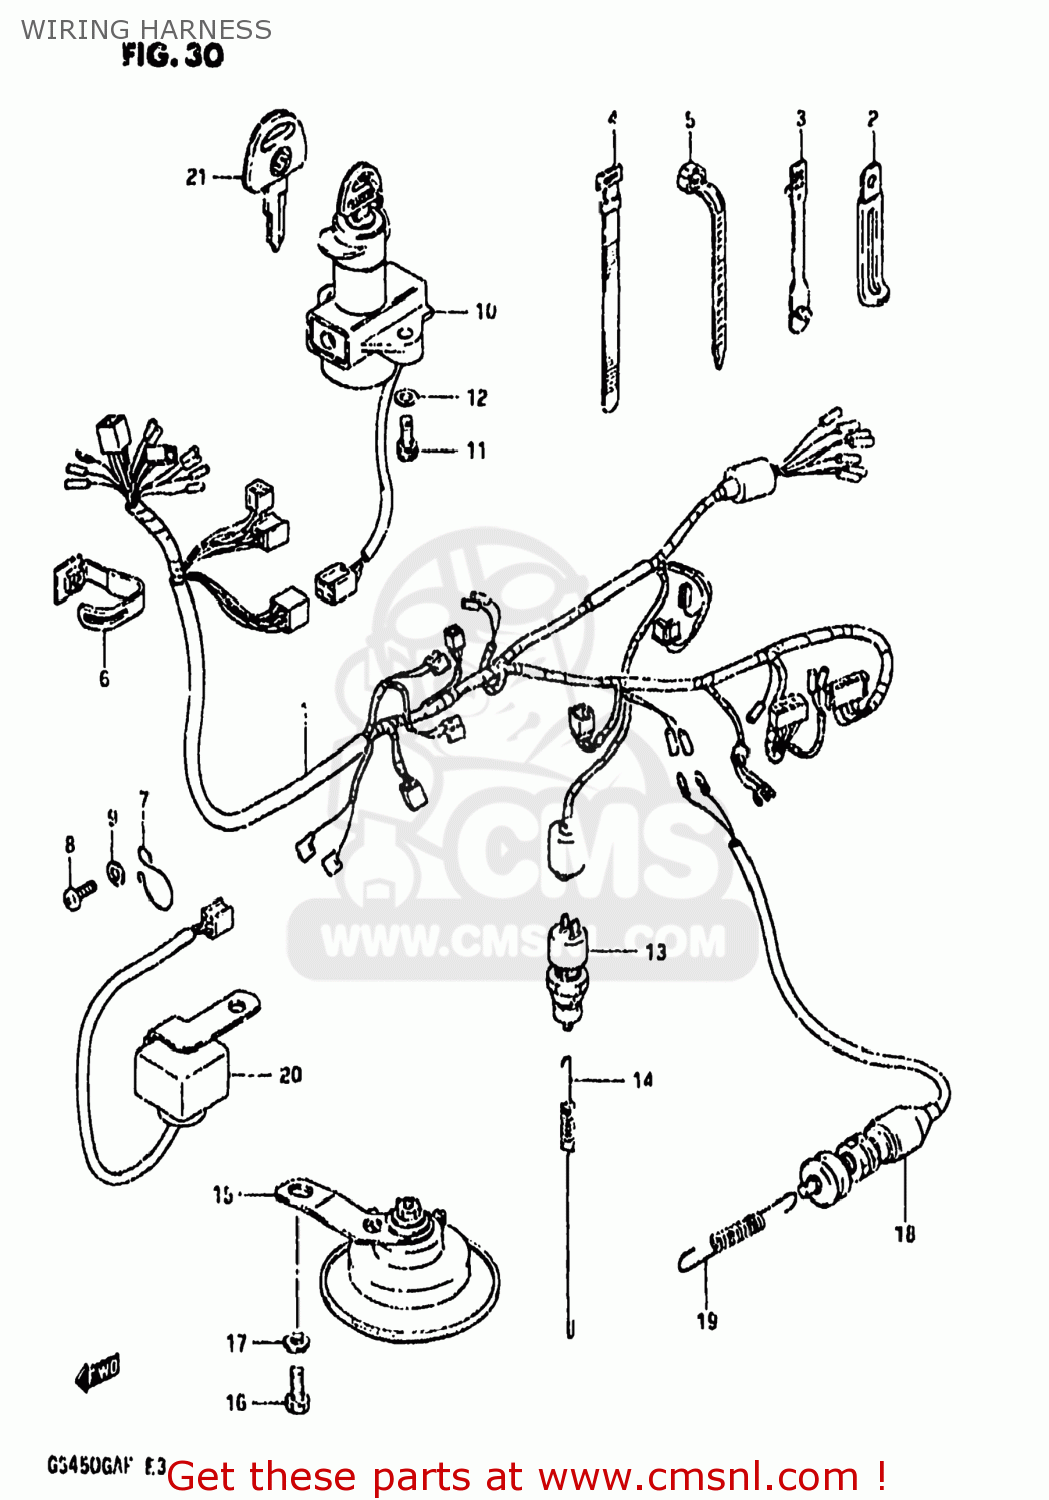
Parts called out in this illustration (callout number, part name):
1	HARNESS,WIRING
2	CLAMP
3	CLAMP,L:88
4	CLAMP(L:80)
5	CLAMP(L:125)
6	CLAMP,WIRING HARNESS
7	CLAMP,WIRING HARNESS
8	CLAMP,WIRING HARNESS
9	CLIP,WIRING HARNESS
10	SCREW 6X12
11	WASHER
12	IGNITION SWITCH/STEERING LOCK
13	BOLT
14	LOCK WASHER
15	SWITCH ASSEMBLY,STOP LAMP
16	SPRING
17	HORN ASSEMBLY
18	BOLT 8X12
19	WASHER 8MM
20	SWITCH ASSEMBLY,SIDE STAND
21	SPRING
22	BUZZER ASSEMBLY,TURN SIGNAL
23	KEY,BLANK
